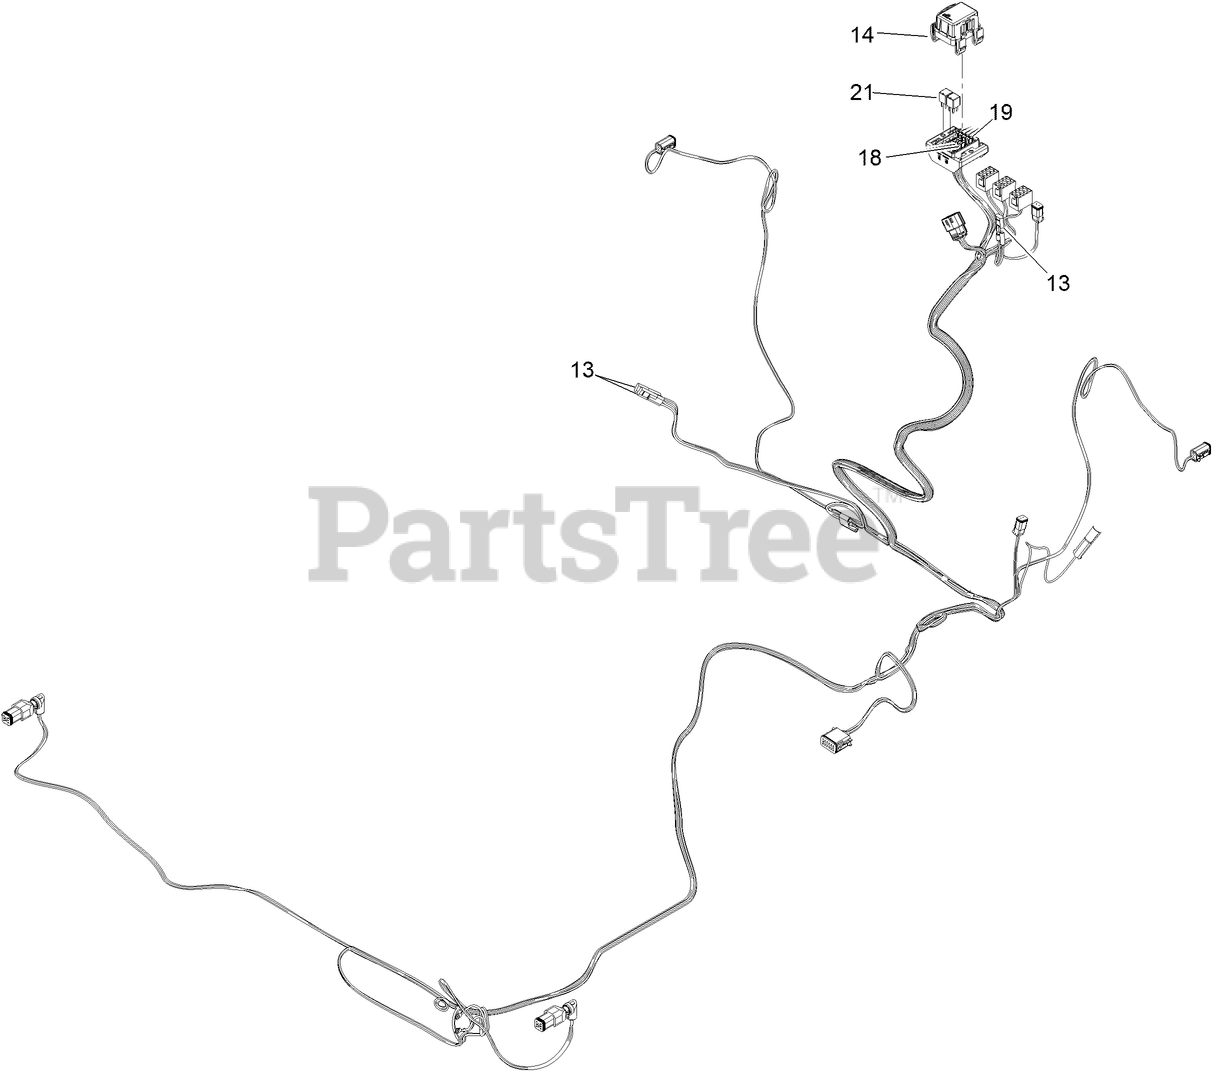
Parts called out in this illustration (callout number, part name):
13	CAP-PLUG
14	COVER-FUSEBLOCK
18	FUSE-MINI BLADE, 2 AMP
19	FUSE-MINI BLADE, 5 AMP
21	RELAY-MICRO
